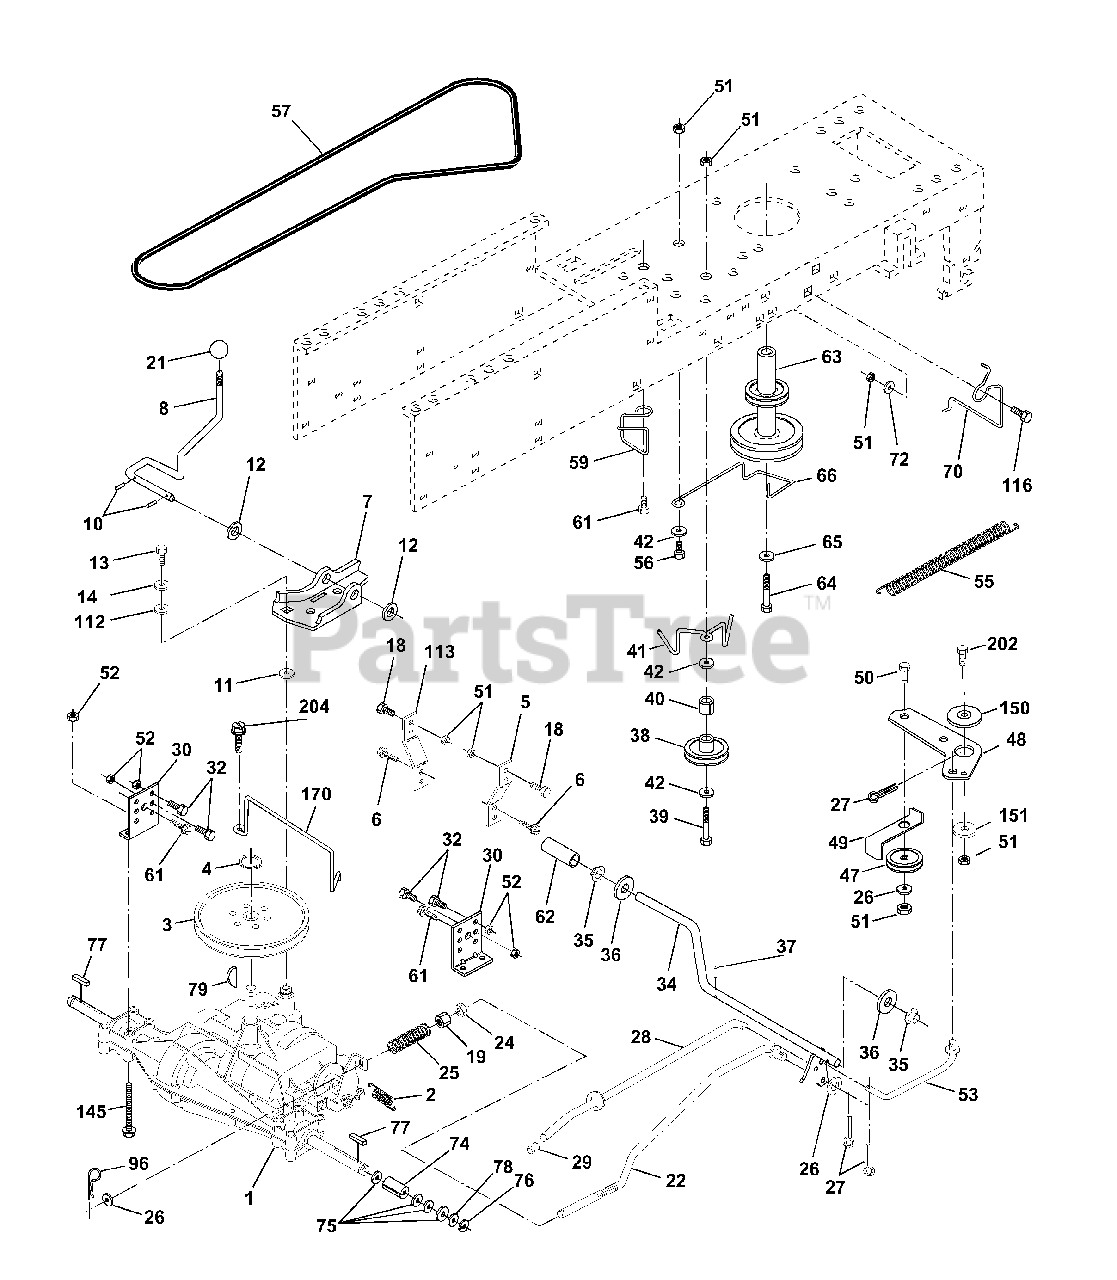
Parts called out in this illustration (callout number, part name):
2	Spring Return Brake
3	Pulley Transaxle 18" tires
4	Ring Retainer # 5100-62
5	Strap Torque 30 Degrees RH
6	Screw 5/16-18 x 3/4
7	Plate Rod Shift T/a
8	Rod Shifter Blk
10	Pin Cotter 1/8 X 1 Cad
11	Washer Plate Shf 388 Sq Hole
12	Washer 15/32 X 3/4 X 16 Ga
13	Bolt 1/4-28 unf Gr. 8 w/Patch
14	Washer Lock Hvy Helical 1/4
18	Bolt Fin Hex 3/8-16unc X 1 Gr. 5
19	Nut lock Hex w/Ins 3/8-16 Unc
21	Knob Rd 1/2-13 Plstc Thds Blk
22	Rod Brake LT
24	Nut Hex Jam 3/8-16 Unc
25	Spring Rod Brake 2 00 Zinc
26	Washer 13/32 X 13/16 X 16 Ga
27	Pin Cotter 1/8 X 3/4 Cad
28	Rod Brake Parking LT/YT
29	Cap Brake Parking Black
30	Bracket Transmission
32	Bolt Fin Hex 5/16-18 x 3/4
34	Shaft Asm Pedal Foot
35	Bearing Nylon Blk 629 Id
36	Washer 21/32 X 1 X 16 Ga
37	Pin Roll 3/16 X 1"
38	Pulley Idler Flat
39	Bolt Rdhd 3/8-16 Unc x 2-3/4 Gr.5
40	Spacer Split 395 X 59 Bzp
41	Keeper Belt Idler
42	Washer 13/32 X 13/16 X 12 Ga
47	Pulley Idler V Groove Plastic
48	Bellcrank Clutch Grnd Drv STL
49	Retainer Belt Style Spring
50	Bolt Hex Hd 3/8-16unc X 1-1/2
51	Nut Crownlock 3/8-16 Unc
52	Nut Crownlock 5/16-18 unc
53	Link Clutch 7 66
55	Spring Return Clutch 6 75
56	Bolt Fin Hex 3/8 X 16 x 1-1/4
57	V-Belt Ground Drive 95
58	Keeper Belt RH LT Pnt/zinc 16g
59	Keeper Belt Chassis Span Ctr
61	Screw 3/8-16 x 3/4
62	Cover Pedal Blk Round
63	Engine Pulley LT/YT
64	Bolt Hex 7/16-20x4 Gr 5
65	Washer Lock Hvy Hlcl Spr 7/16
66	Keeper Belt Engine
70	Guide Belt Mower Drive RH
72	Washer 13/32 X 1-1/4 X 12 Ga
74	Spacer Axle
75	Washer 25/32 X 1 1/4 X 16 Ga
76	E-ring #5133-75
77	Key Square 2 0 X 1845/ 1865
78	Washer 25/32 X 1-5/8 X 16 Ga
79	Key Woodruff
96	Retainer Spring 1"
112	Washer 9/32 X 3/4 X 10 Ga
113	Strap Torque 90 Degrees LH
116	Bolt Rdhd Sq Neck 3/8-16 x 1.25
145	Bolt Hex Flg.Hd. 5/16-18 x Gr.5
150	Bushing Bellcrank
151	Washer 13/32 x 2 x 10 Ga.
202	Bolt Carr Sh 3/8-16 x 1-1/2 Gr.5
204	Screw 5/16-18 x 1
